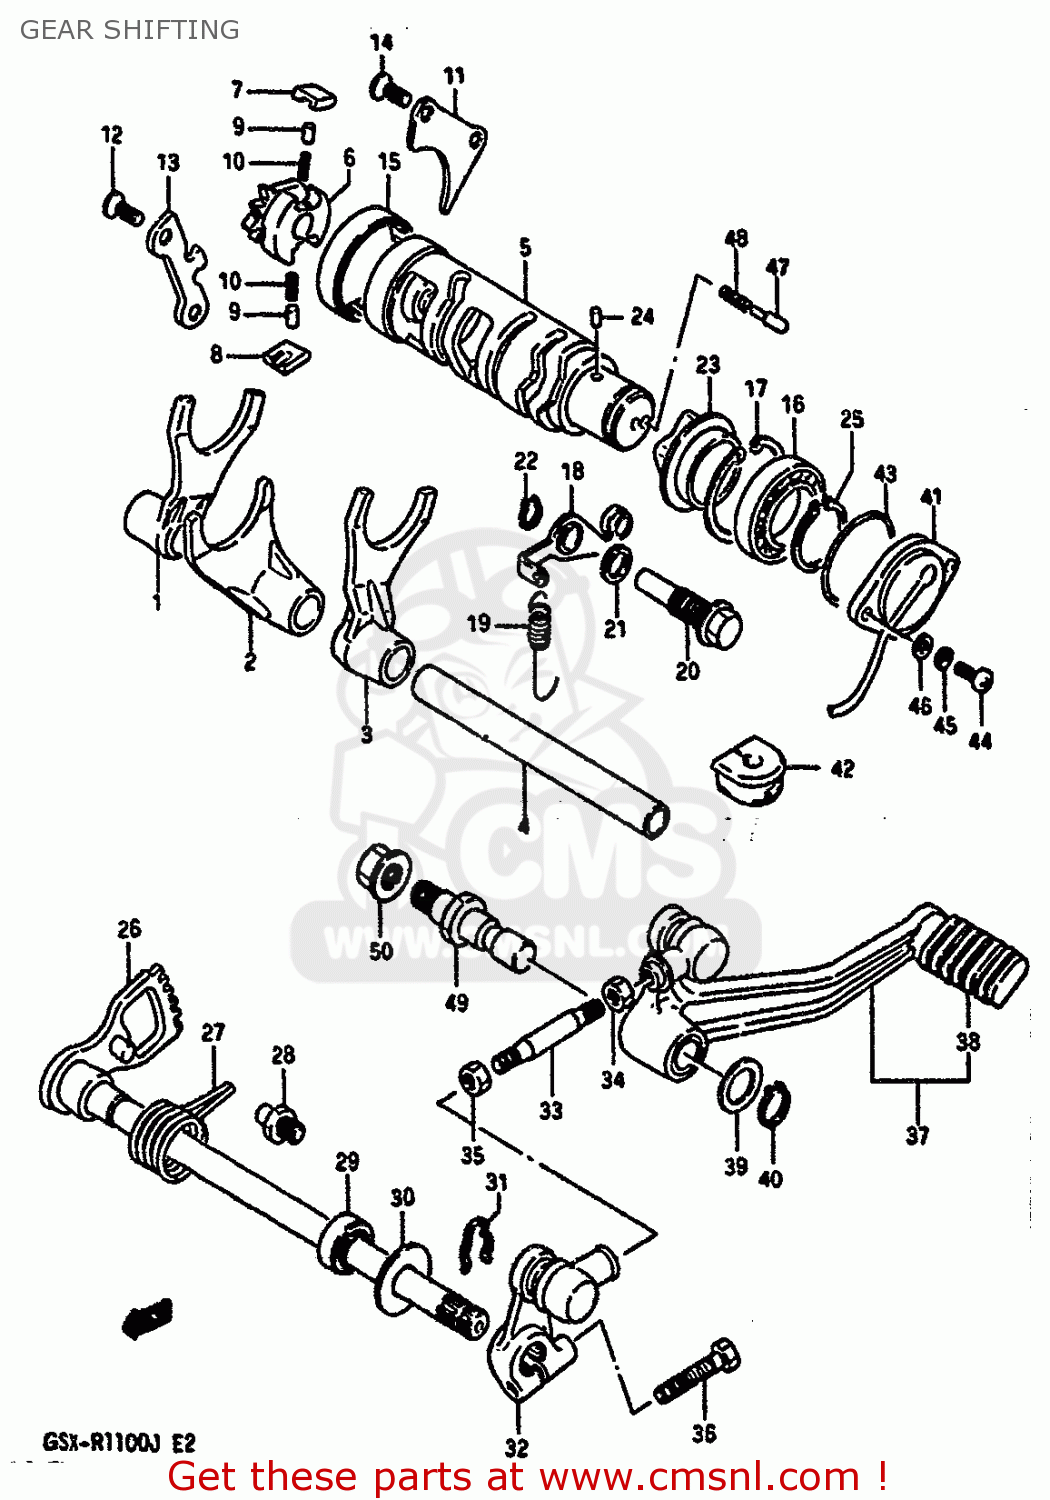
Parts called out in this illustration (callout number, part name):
1	FORK,GEAR SHIFT NO.1
2	FORK,GEAR SHIFT NO.2
3	FORK,GEAR SHIFT NO.3
4	SHAFT,GEAR SHIFT FORK(L:128)
5	CAM,GEAR SHIFT
6	GEAR,GEARSHIFT CAM DRIVE
7	PAWL,GEAR SHIFT NO.1
8	PAWL,GEAR SHIFT NO.2
9	PIN(5X8)
10	SPRING
11	LIFTER,GEAR SHIFT PAWL
12	SCREW
13	GUIDE,GEAR SHIFT CAM
14	SCREW
15	BEARING(43X49X12)
16	BALL BEARING
17	CIRCLIP,42MM
18	STOPPER,GEAR SHIFT CAM
19	SPRING
20	SHAFT,GEAR SHIFT CAM STOPPER
21	GASKET(10X14X3.6) (NAS)
22	CIRCLIP
23	PLATE,STOPPER
24	PIN 4X6
25	CIRCLIP,25MM
26	SHAFT,GEAR SHIFT
27	SPRING
28	STOPPER,GEAR SHIFT CAM
29	OIL SEAL
30	WASHER (12.5X27X1.6)
31	SPRING,RETAINER
32	ARM,GEAR SHIFT
33	ROD,GEAR SHIFT LINK
34	NUT
35	NUT 6MM
36	BOLT
37	LEVER ASSY,GEAR SHIFT
38	RUBBER,BRAKE PEDAL
39	WASHER(12.5X20X1)
40	CIRCLIP
41	TERMINAL BASE ASSY,NEUTRAL
42	GROMMET,LEAD WIRE
43	O RING(D:2.4,ID:36.5)
44	SCREW(5X14)
45	LOCK WASHER
46	WASHER
47	PIN(5X15.5)
48	SPRING
49	SHAFT,GEAR SHIFT LEVER
50	NUT
